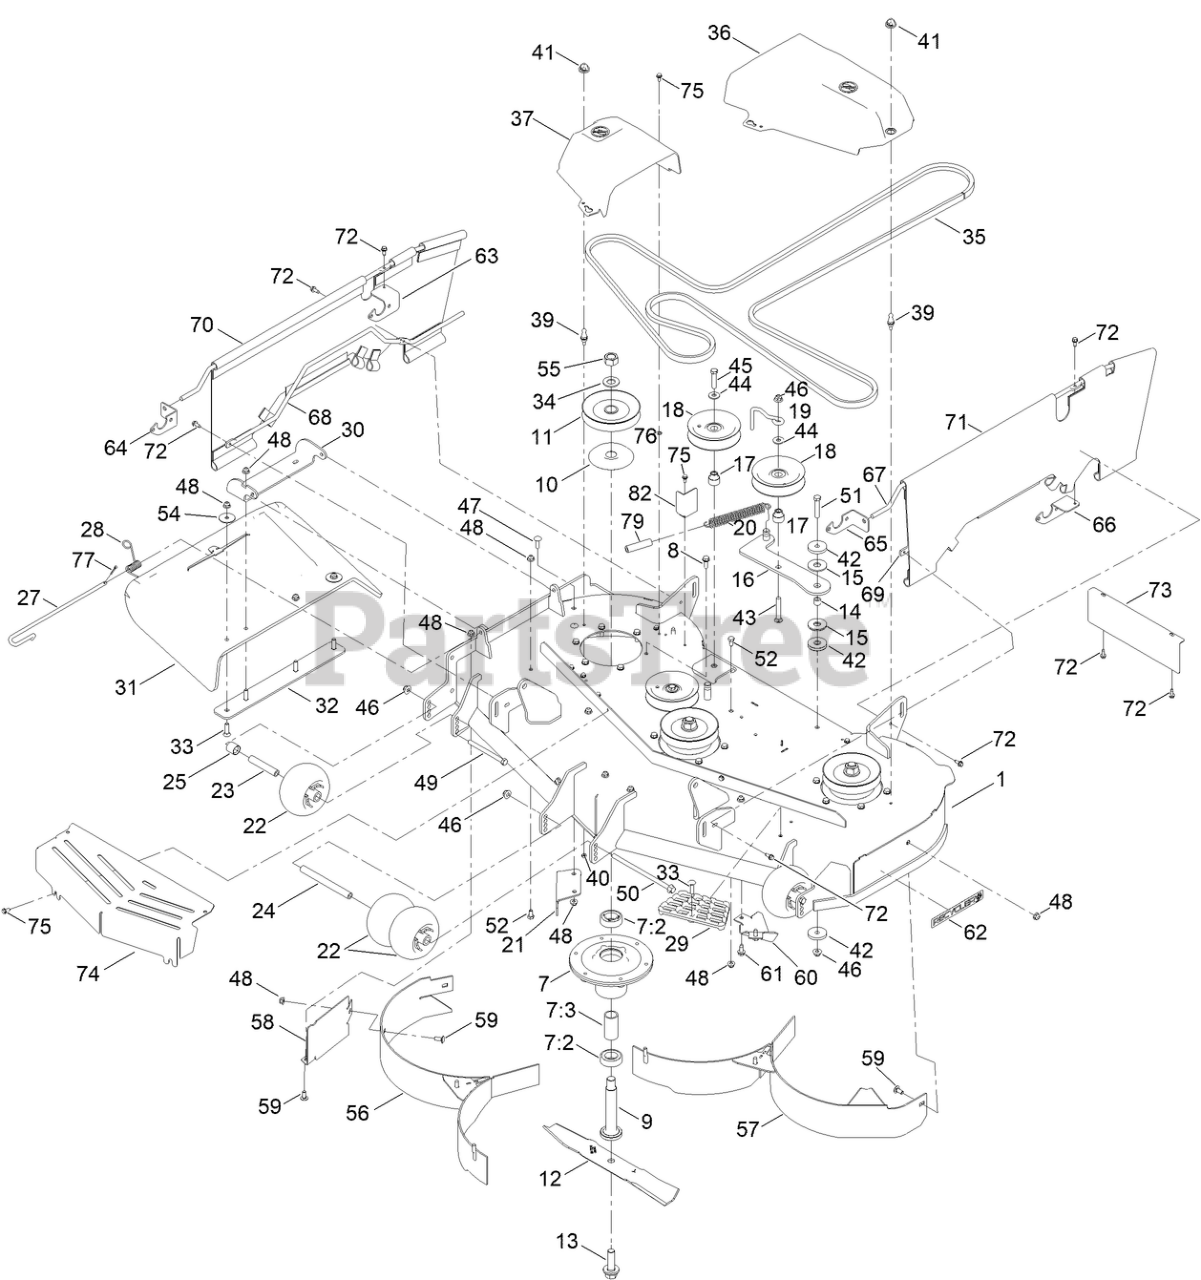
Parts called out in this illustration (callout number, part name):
1	48 IN DECK DECAL ASM
7	SPINDLE ASM
7:2	BEARING-BALL
7:3	SPACER-BEARING
8	SCREW-TAPTITE
9	SHAFT-SPINDLE
10	SHIELD-BEARING
11	PULLEY
12	BLADE-MULCH, 16.50 INCH
13	SCREW-BLADE
14	SPACER
15	WASHER-FRICTION, COMPOSITE
16	IDLER ARM ASM
17	BUSHING-IDLER
18	PULLEY-IDLER, FLAT
19	GUIDE-BELT, IDLER
20	SPRING-EXTENSION
21	BAFFLE-CUTOFF
22	ROLLER-SCALP, ANTI
23	TUBE-SPANNER
24	SPACER-WHEEL
25	SPACER-AXLE, REAR
27	PIN-CHUTE
28	SPRING-TORSION
29	STEP-DECK
30	BRACKET-DEFLECTOR, UPPER
31	DEFLECTOR - MOLDED
32	PLATE-DEFLECTOR
33	BOLT-CARRIAGE
34	WASHER
35	V-BELT
36	COVER-BELT, LH
37	COVER-BELT, RH
39	STUD-BALL
40	NUT-LOCK
41	GROMMET-BALL
42	WASHER-PLAIN
43	SCREW-CARR
44	WASHER-HARDENED
45	SCREW-HH
46	NUT-HF, NI
47	SCREW-CARR
48	NUT-HF
49	SCREW-HH
50	SCREW-HF
51	HHCS 3/8-16 X 2, GR5, CZ
52	SCREW-HH
54	WASHER-FLAT
55	NUT-HEX
56	BAFFLE-RECYCLER
57	BAFFLE-RECYCLER
58	GUARD-BAFFLE
59	BOLT-CARR
60	KICKER-FLANGED
61	SCREW-HWHTF
62	DECAL-RECYCLER
63	BRACKET-FRENCH GUARD
64	BRACKET-FRENCH GUARD
65	BRACKET-FRENCH GUARD
66	BRACKET-FRENCH GUARD
67	ROD-FRENCH GUARD
68	ROD-FRENCH GUARD
69	ROD-FRENCH GUARD
70	GUARD ASM-SIDE, POLY KNIT
71	GUARD ASM-SIDE, POLY KNIT
72	SCREW-HWH
73	PLATE-GUARD REAR
74	BRKT-SHIELD, FRONT
75	SCREW-HWH
76	NUT-RETAINING
77	PIN-COTTER
79	HOSE-BREATHER
82	BRACKET-GUARD, CE
